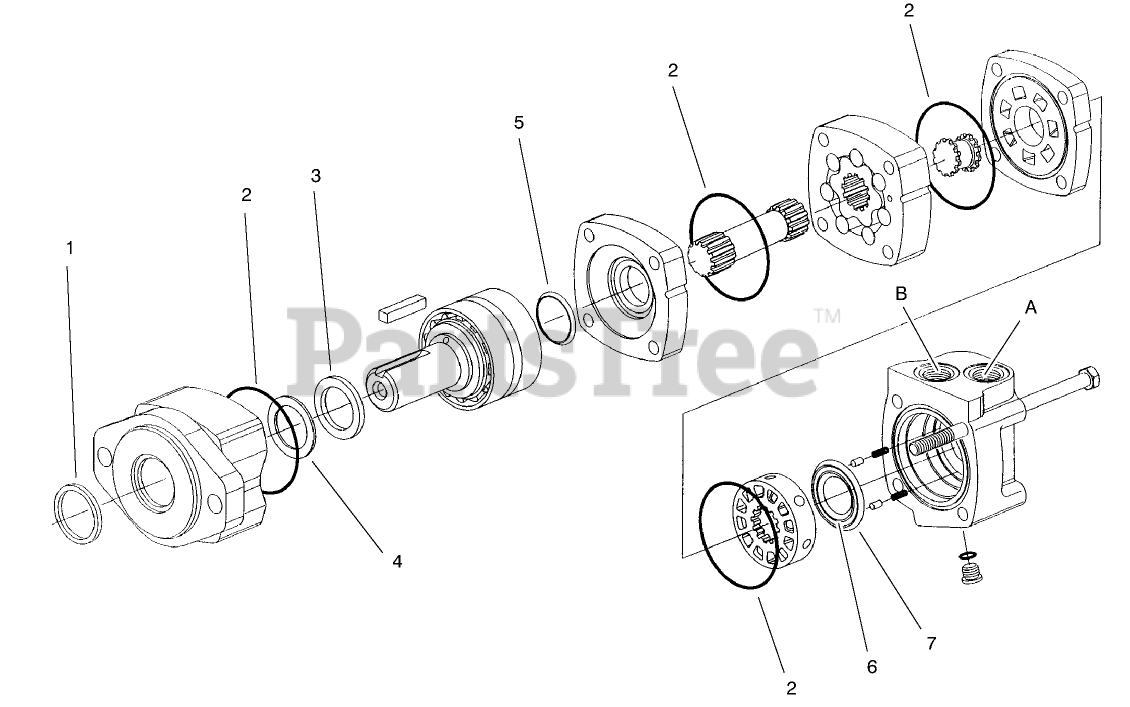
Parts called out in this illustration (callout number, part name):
2	Seal-O-Ring
4	Back-Up Washer
7	Seal-Outer
